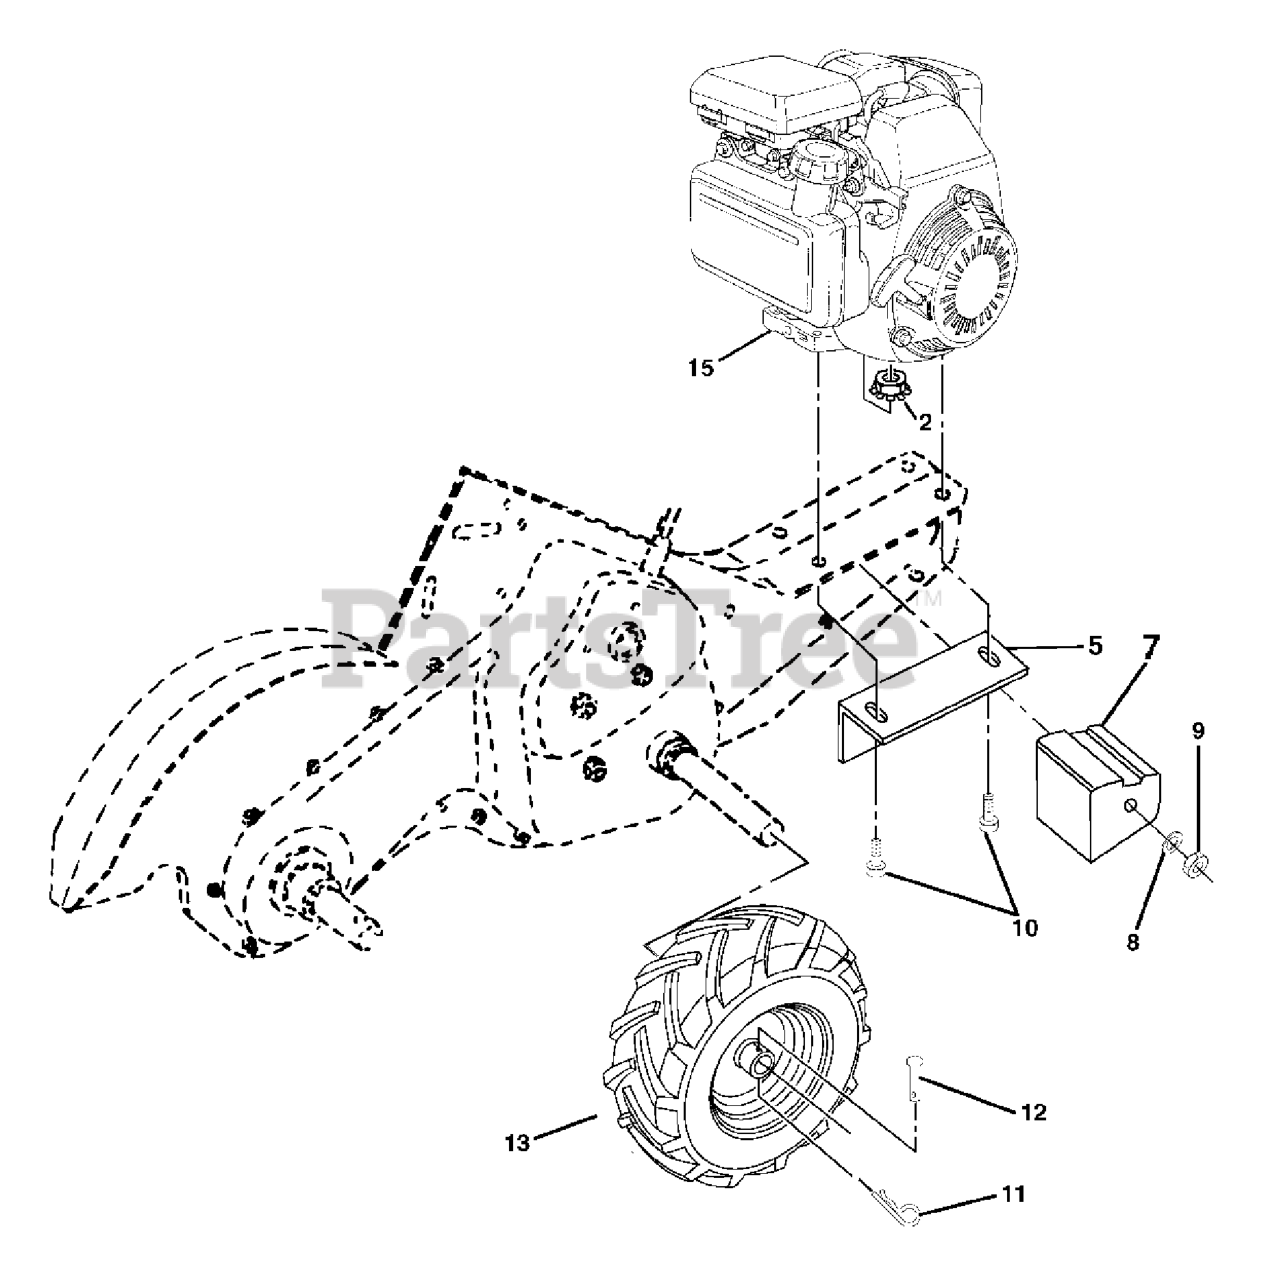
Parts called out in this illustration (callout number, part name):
2	LOCKNUT-FLANGE 5/16-18
5	DNO BRACKET RH CRT
7	COUNTERWEIGHT, RH
8	WASHER, LOCK 3/8
9	NUT.HEX.3/8-16UNC
10	BOLT
11	RETAINER M
12	RIVET,DRILLED
13	TIRE.13X5-6.CHEVRON.TILLER
13	RIM.ASM.6".SILVER
13	VALVE STEM LT
